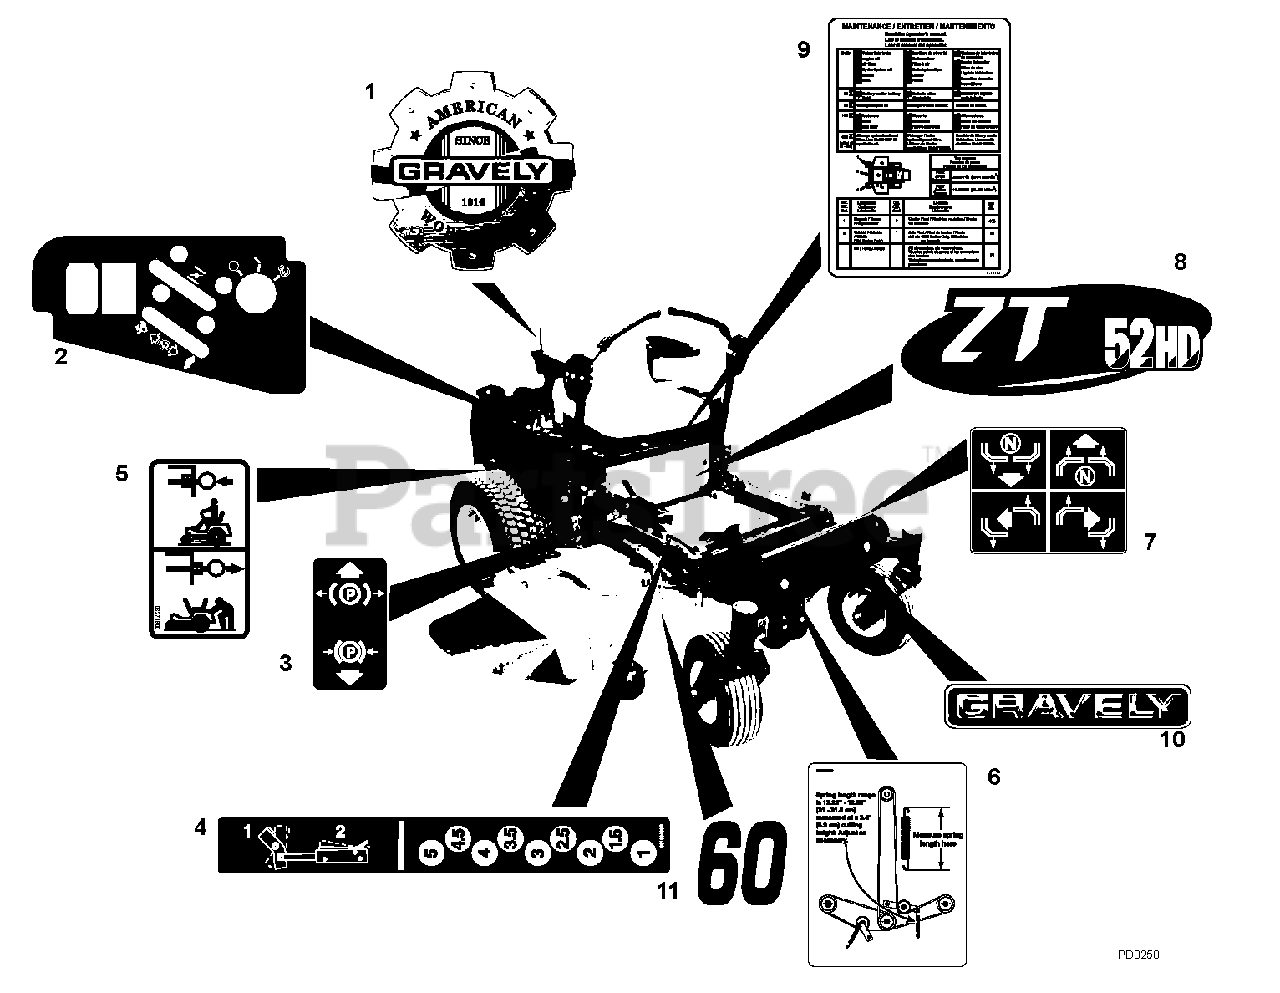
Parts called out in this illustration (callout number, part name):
1	Decal, Gravely Heritage Small
2	Decal, Control Panel
3	Decal, Parking Brake Lever
4	Decal, Height of Cut
5	Decal, Transmission Disconnect
6	Decal, Belt Diagram
7	Decal, Instructional Steering
8	Decal, 44 HD (991090)
8	Decal, 48 HD (991082)
8	Decal, 52 HD (991083)
8	Decal, 60 HD (991084)
9	Decal, Maintenance Instructions
10	Decal, 13.50" Gravely Logo
11	Decal, 60" (991084)
11	Decal, 52" (991083)
11	Decal, 48" (991082)
11	Decal, 44" (991090)
